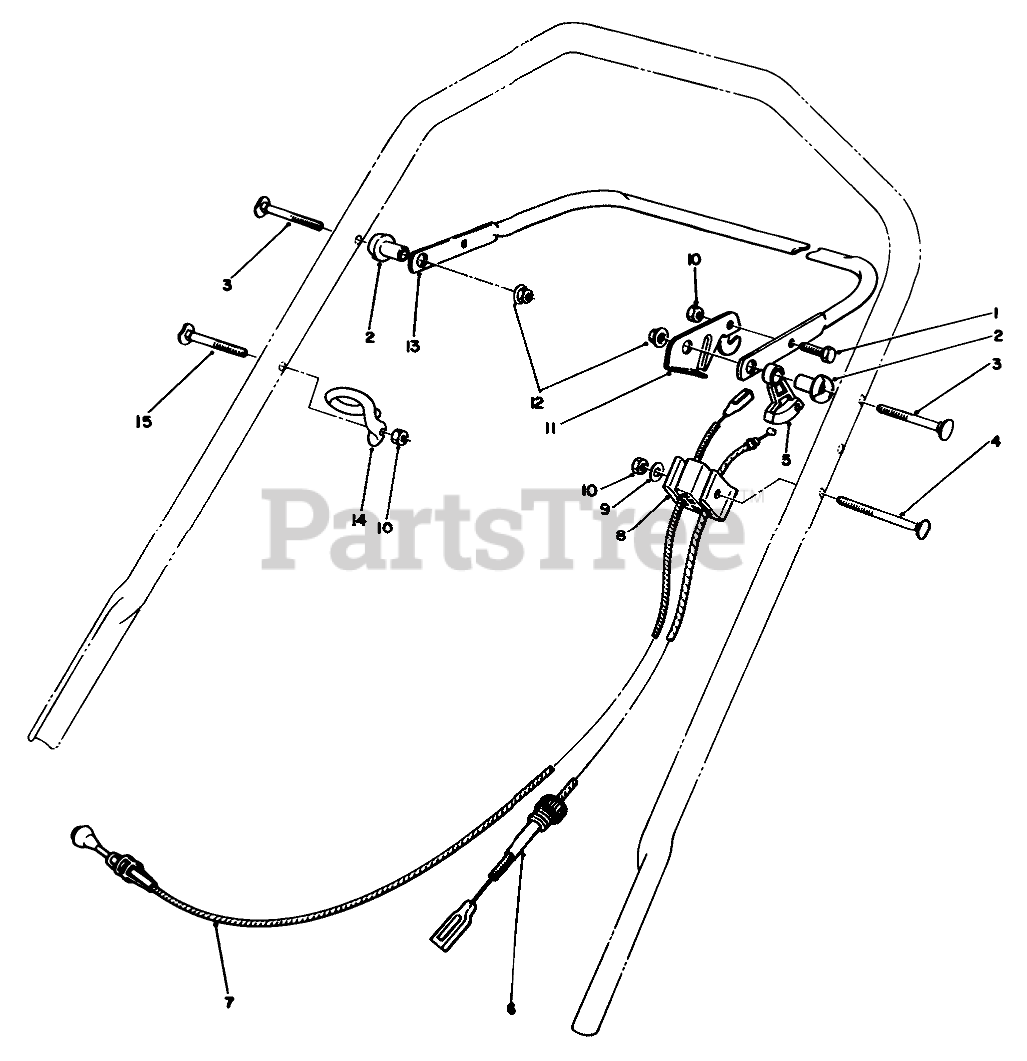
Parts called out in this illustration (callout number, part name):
1	SCREW-HH
2	SPACER-SUPPORT
3	5/16-18 X 2 HNDLE SCREW
4	HANDLE SCREW
5	LEVER-TRACTION
6	CABLE-TRACTION
7	BRAKE CABLE
8	SUPPORT-CABLE
9	WASHER-FLAT
10	NUT-LOCK, NI
11	LEVER-CONTROL
12	NUT-LOCK, NI
13	Bar-Control
14	Guide
15	HANDLE SCREW
